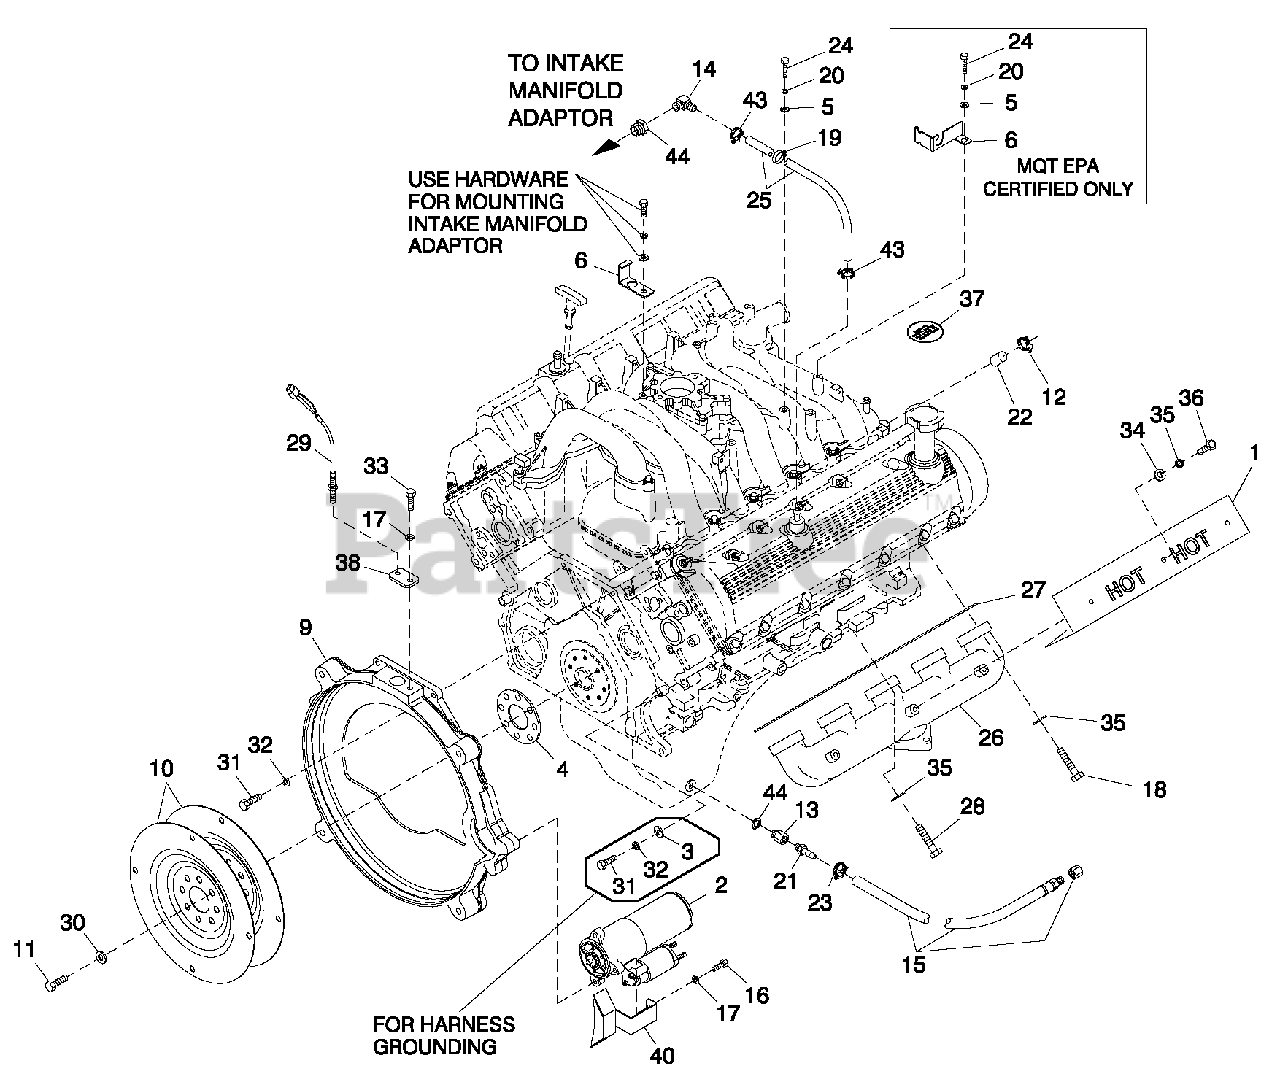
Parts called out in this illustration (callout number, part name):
1	HEAT SHIELD EXHAUST
2	STARTER MOTOR FORD V-10 ENGINE
3	WASHER FLAT 3/8-M10 ZINC
4	SPACER FLEXPLATE 5.4L/6.8L (1800 RPM UNITS ONLY)
5	WASHER FLAT 1/4-M6 ZINC
6	BRACKET SIGNAL CONDITIONER
8	WASHER NYLON .565
9	ENGINE ADAPTER 5.4L/6.8L
10	FLEX PLATE 2 POLE (1800 RPM UNITS ONLY)
11	SCREW HHC M10-1.0 X 25 G10.9
12	CLAM P HOSE #10 .56 - 1.06 (1800 RPM UNITS ONLY)
13	ADAPTER M14-1.50X 3/8 N PT
14	BARBED EL 90 3/8N PTX5/8
15	HOSE DRAIN ASSY 28"
16	SCREW HHC M8-1.25X30 G8.8
17	WASHER LOCK M8-5/16
18	SCREW SHC M8-1.25X 35 SS
19	CLAM P VINYL .75X.343Z
20	WASHER LOCK M6-1/4
21	BARBED STR3/8N PTX3/8
22	CA P HOSE (1800 RPM UNITS ONLY)
23	CLAM P HOSE .38-.87
24	SCREW HHC M6-1.0X 16 G8.8
25	HOSE COOL 5/8" ID 250#W P (14")
26	EXH MANIFOLD MACH 6.8L V-10
27	GASKET EXHAUST MANIFOLD
28	SCREW HHC M8-1.25 X 35 SS G8.8
29	ASSY MAG PICKUP (3/8-24 MALE)
30	WASHER FLAT .43X1.00
31	SCREW SHC M10-1.5 X 25 G12.9
32	WASHER LOCK M10
33	SCREW HHC M8-1.25X20 G8.8
34	WASHER FLAT M8 SS
35	WASHER LOCK M8 SSTL
36	SCREW HHC 5/16-18 X 1/2 SSTL
37	DECAL REFER TO OWNERS MANUAL
38	PLATE MAG PICK-U P ADAPTOR
40	COVER STARTER 5.4 & 6.8 FORD CPL
43	CLAM P HOSE #10 .56-1.06
44	ADAPTOR 1/4" N PT TO 3/8" N PT
